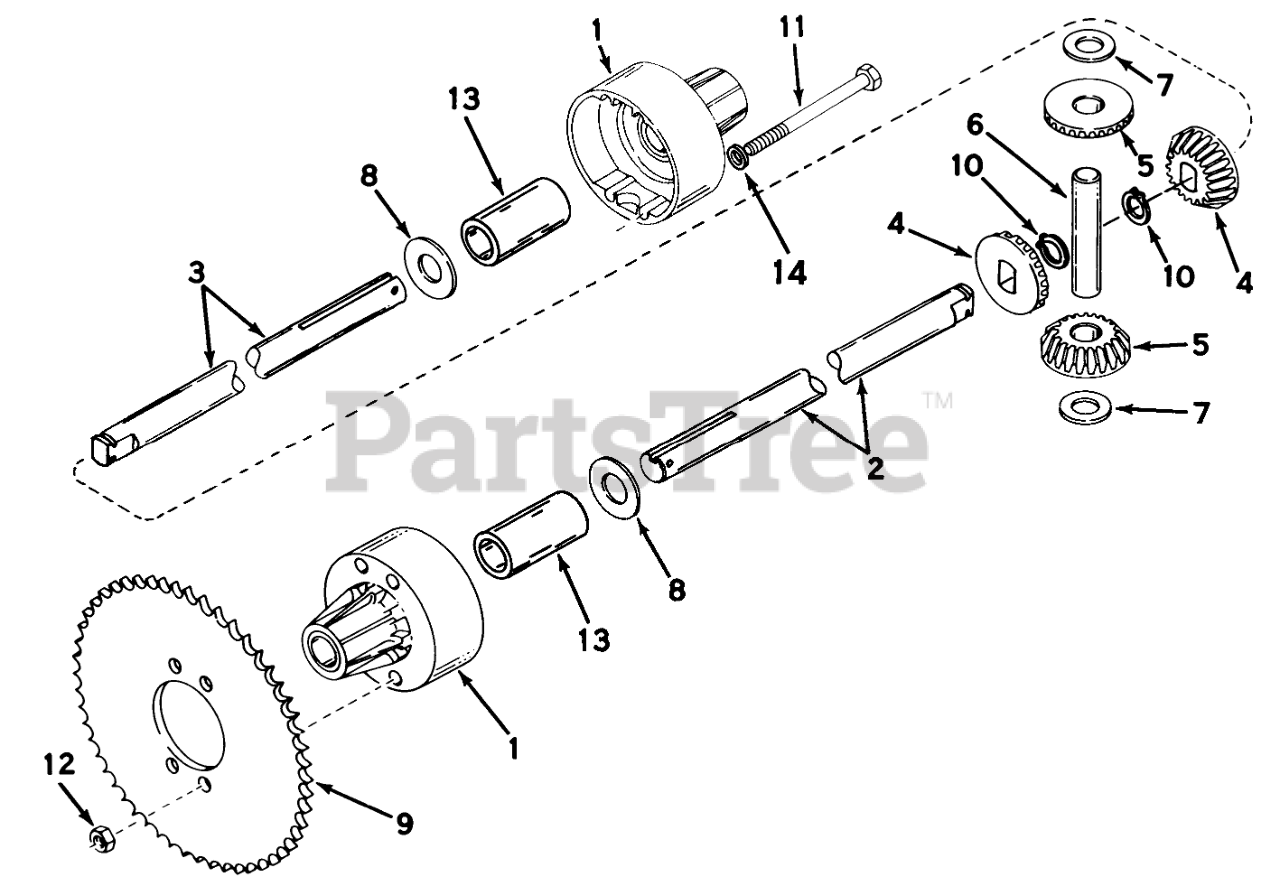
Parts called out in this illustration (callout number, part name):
1	Housing, Differential carrier (Incl. No. 13)
2	Axle (10 7/32" Long)
3	Axle (15 3/32" Long)
4	Bevel Gear
5	Gear Pinion
6	Pin Drive
7	Washer Thrust
8	Washer
9	Sprocket (40 teeth)
10	Snap Ring
11	Screw-Hex Hd.
12	Nut-Lock
13	Bushing
14	Washer
